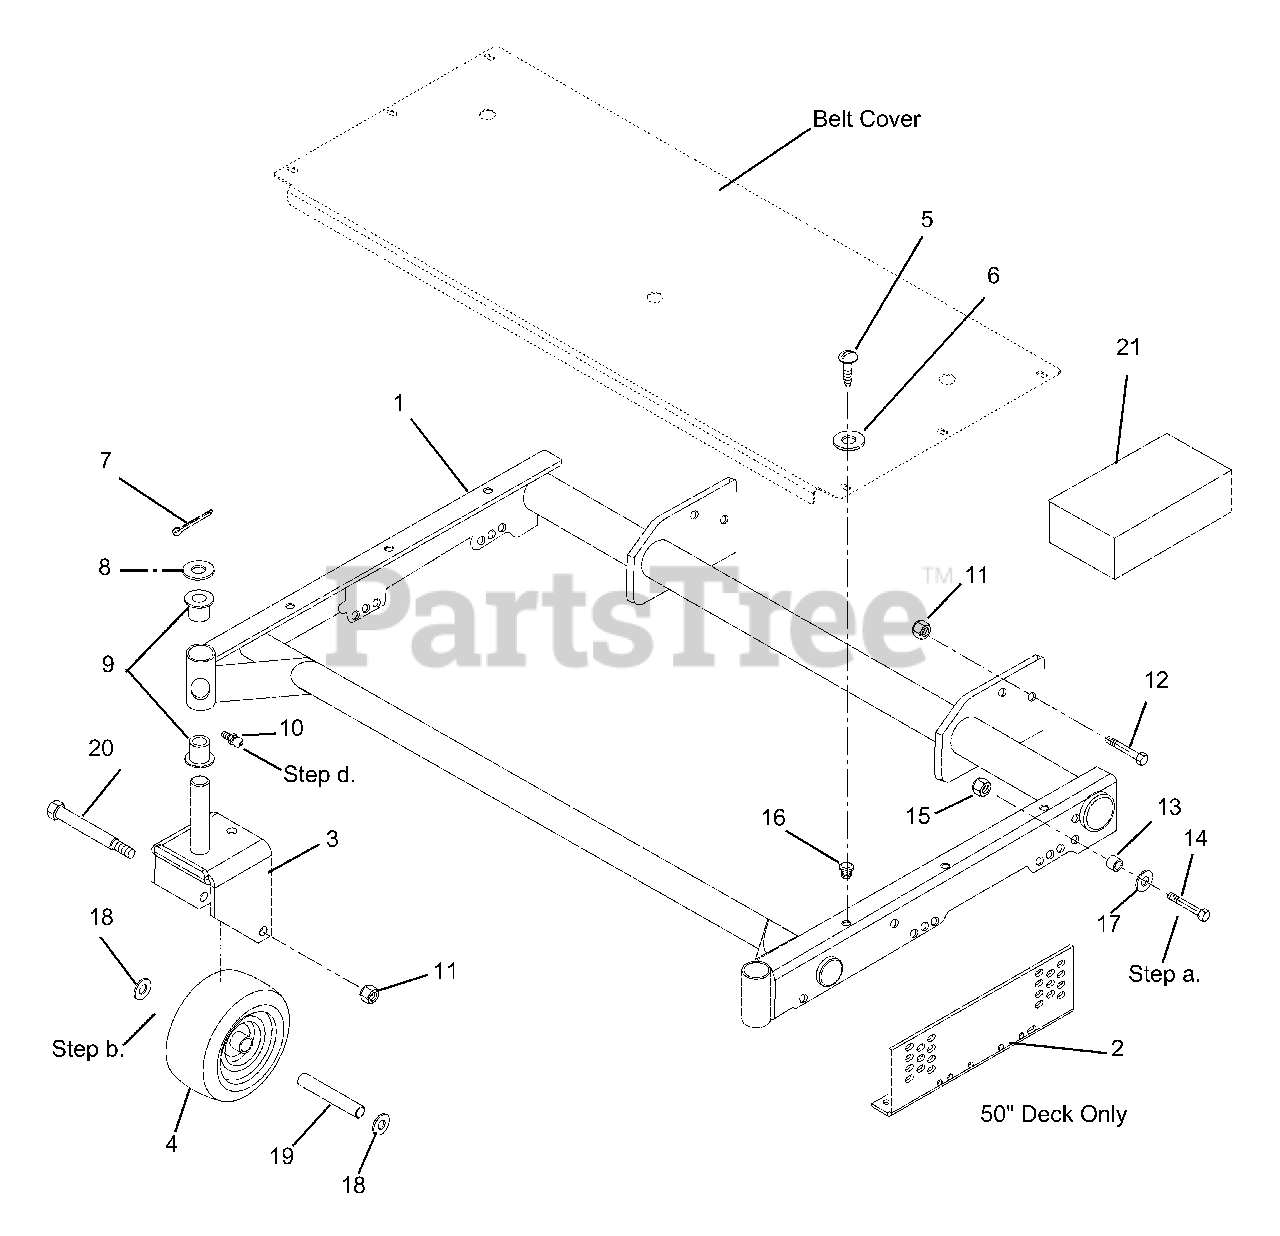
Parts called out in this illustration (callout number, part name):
1	WELDMENT, FRAME 50"
2	BRACKET, MOW.SIDE SUPP. RH
3	WELDMENT, CASTER FORK
4	WHEEL ASSEMBLY 9.00 X 3.50
5	SCR-TAP .250-20X.50 HXSLHDPL
6	@WSHR-FL-STL.281X.62X.065 YWZC
7	@PIN-CTR .18X1.50 EXTPRSQCT YZ
8	WSHR-HDND-THRUST 1.00X1.55X.03
9	BSHG-FLG1.020X1.385X.75X1.75NY
10	FTG-LUBE .25-28X.256 YWZC
11	@NUT-LK-NYL .50-13 YWZC
12	@BLT-HEX .50-13X1.50 GR5 YWZC
13	BUSHING .391 X .626 X .670
14	@BLT-HEX .38-16X1.50 GR5 YWZC
15	@NUT-LK-NYL .38-16 YWZC
16	GRMT,PLASTIC
17	WSHR-FL-STL .390X1.5X.125 YWZC
18	WSHR-HDND-THRST .760X1.25X.094
19	BEARING .750 X .532 X 3.97
20	@BLT-HEX .50-13X5.50 GR5YWZC
21	KIT, PM300 TRACTOR IDLER
